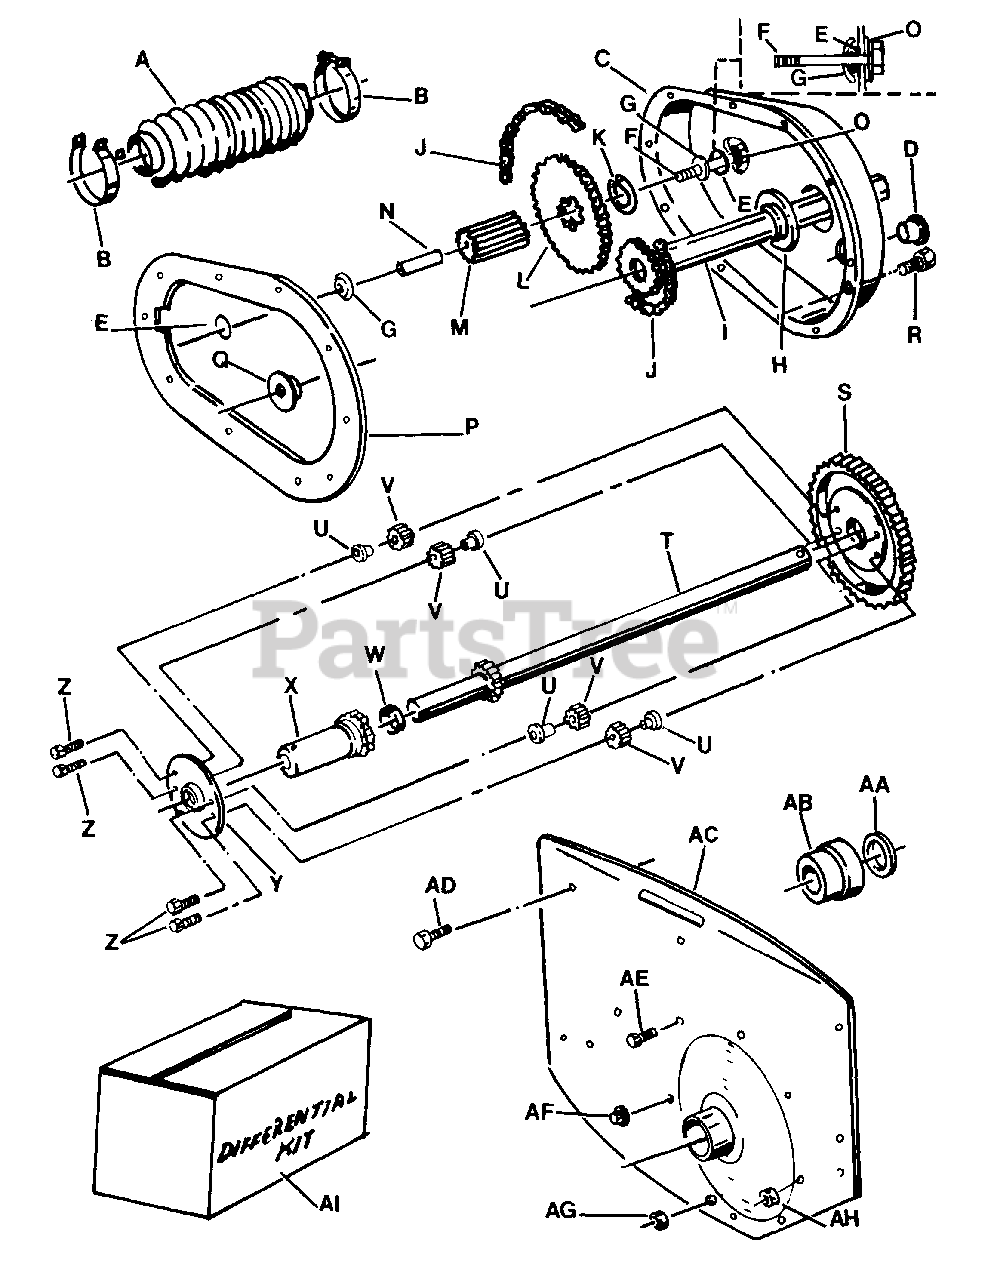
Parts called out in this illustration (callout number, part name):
A	BOOT
B	CLAMP, BOOT
C	CASE, TRANSMISSION
D	PLUG, PLASTIC (CUP INSERT)
E	O-RING, 5/16"
F	BOLT, IDLER
G	WASHER, 5/16 BELLEVILLE
H	WASHER, FIBRE
I	ASSEMBLY, Drive Hex Tube
J	CHAIN
K	RING, RETAINING
L	SPROCKET
M	GEAR, 11 TOOTH - 10 PITCH
N	SPACER
O	WASHER, 5/16 INTERNAL TOOTH LOCK
P	GASKET, TRANSMISSION CASE
Q	WASHER, FLANGE
R	SCREW, HEX HEAD CAP 1/4-28x1/2 (2 - ALIGNING)
S	GEAR, 63 TOOTH - 10 PITCH
T	AXLE, LONG
U	SPACER, PINION
V	GEAR, 12 TOOTH - 12 PITCH PINION
W	SPACER, Differential (1.25" ID x .425 Wide)
X	AXLE, SHORT
Y	PLATE, DIFFERENTIAL
Z	SCREW, SPECIAL LOCK 5/16-24 x 1-5/8
AA	WASHER, THRUST
AB	BEARING, R. H. FENDER
AC	FENDER, RIGHT HAND
AD	SCREW, SELF-TAPPING 5/16-18 x 5/8
AE	SCREW, SELF-TAPPING 1/4-20 x 5/8
AF	NUT, 5/16 FLANGE LOCK
AG	NUT, 5/16-24 HEX
AH	NUT, 1/4-28 HEX LOCK
AI	KIT, DIFFERENTIAL ASSEMBLY
